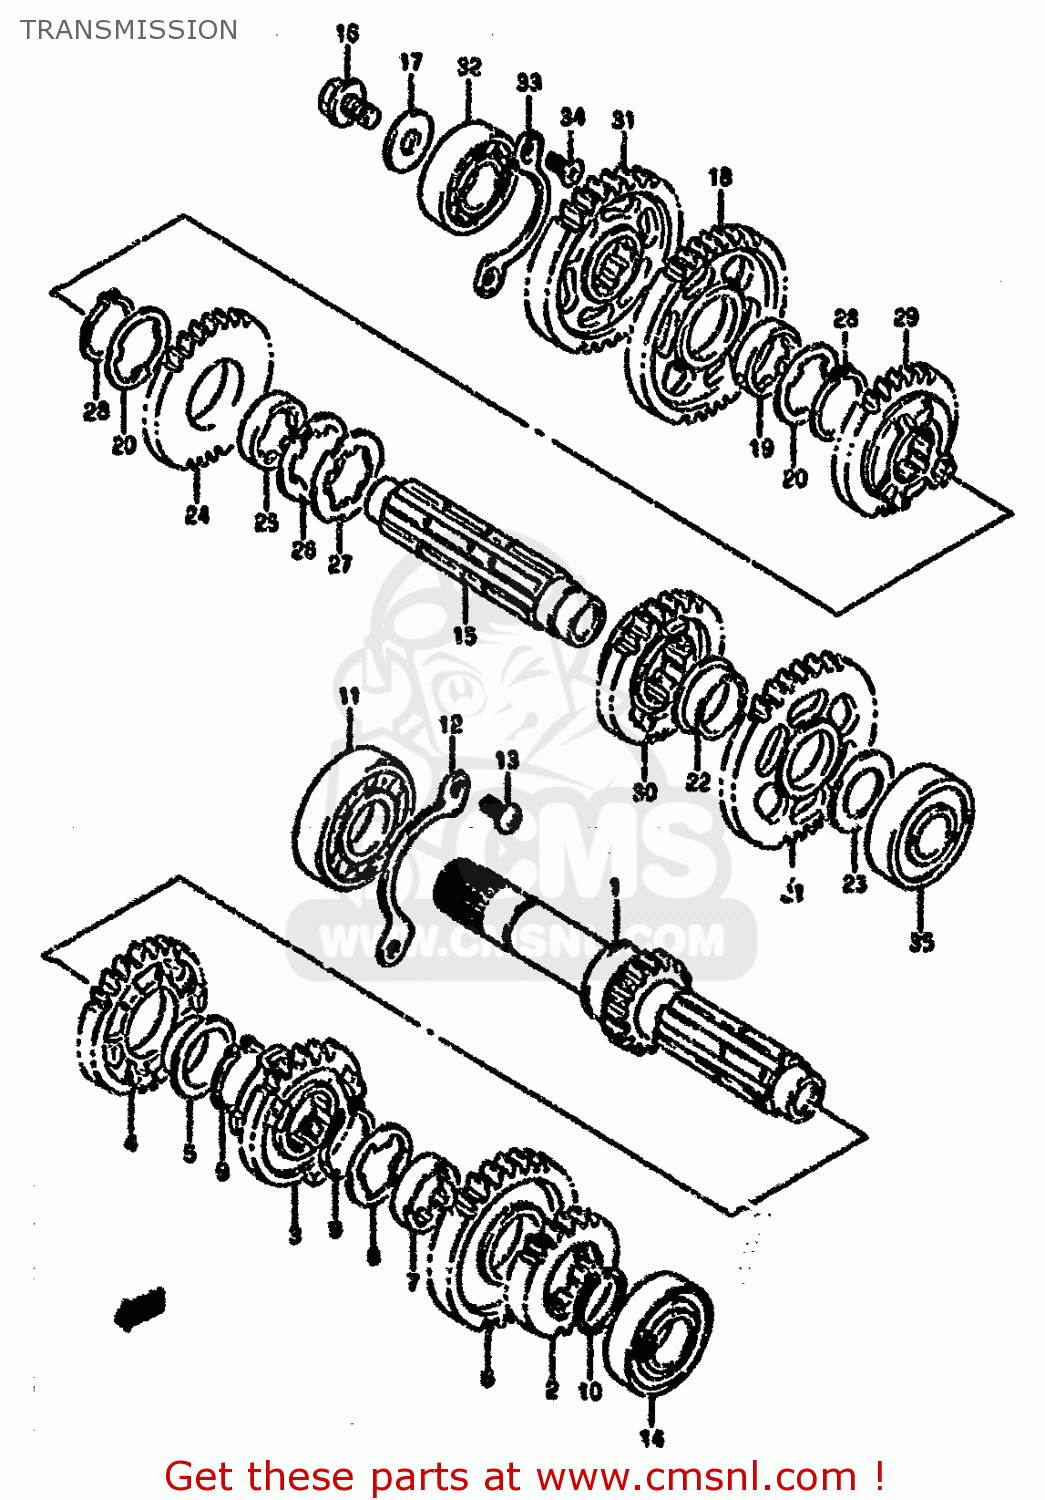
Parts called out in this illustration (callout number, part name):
1	SHAFT COMP,COUNTER
2	GEAR,2ND DRIVE(NT:19)
3	GEAR,3RD DRIVE(NT:22)
4	GEAR,4TH DRIVE(NT:25)
5	BUSHING
6	GEAR,FIFTH DRIVE (NT:27)
7	BUSHING
8	WASHER,LOCK
9	RING,SNAP
10	CIRCLIP
11	BEARING(25X62X17)
12	RETAINER,CNTR SHAFT BEARING
13	SCREW
14	BEARING 20X47X14
15	SHAFT,DRIVE
16	NOZZLE,DRIVE SHAFT
17	WASHER
18	GEAR,1ST DRIVEN(NT:32)
19	BUSH
20	WASHER,LOCK
21	GEAR,2ND DRIVEN(NT:31)
22	BUSH
23	WASHER
24	GEAR,3RD DRIVEN(NT:27)
25	BUSH
26	WASHER
27	WASHER,LOCK
28	CIRCLIP
29	GEAR,4TH DRIVEN(NT:25)
30	GEAR,FIFTH DRIVEN (NT:23)
31	GEAR,OVER DRIVING DRIVE
32	BEARING(20X52X15)
33	RETAINER,DRIVE SHAFT BEARING
34	SCREW
35	BEARING(20X52X15)
